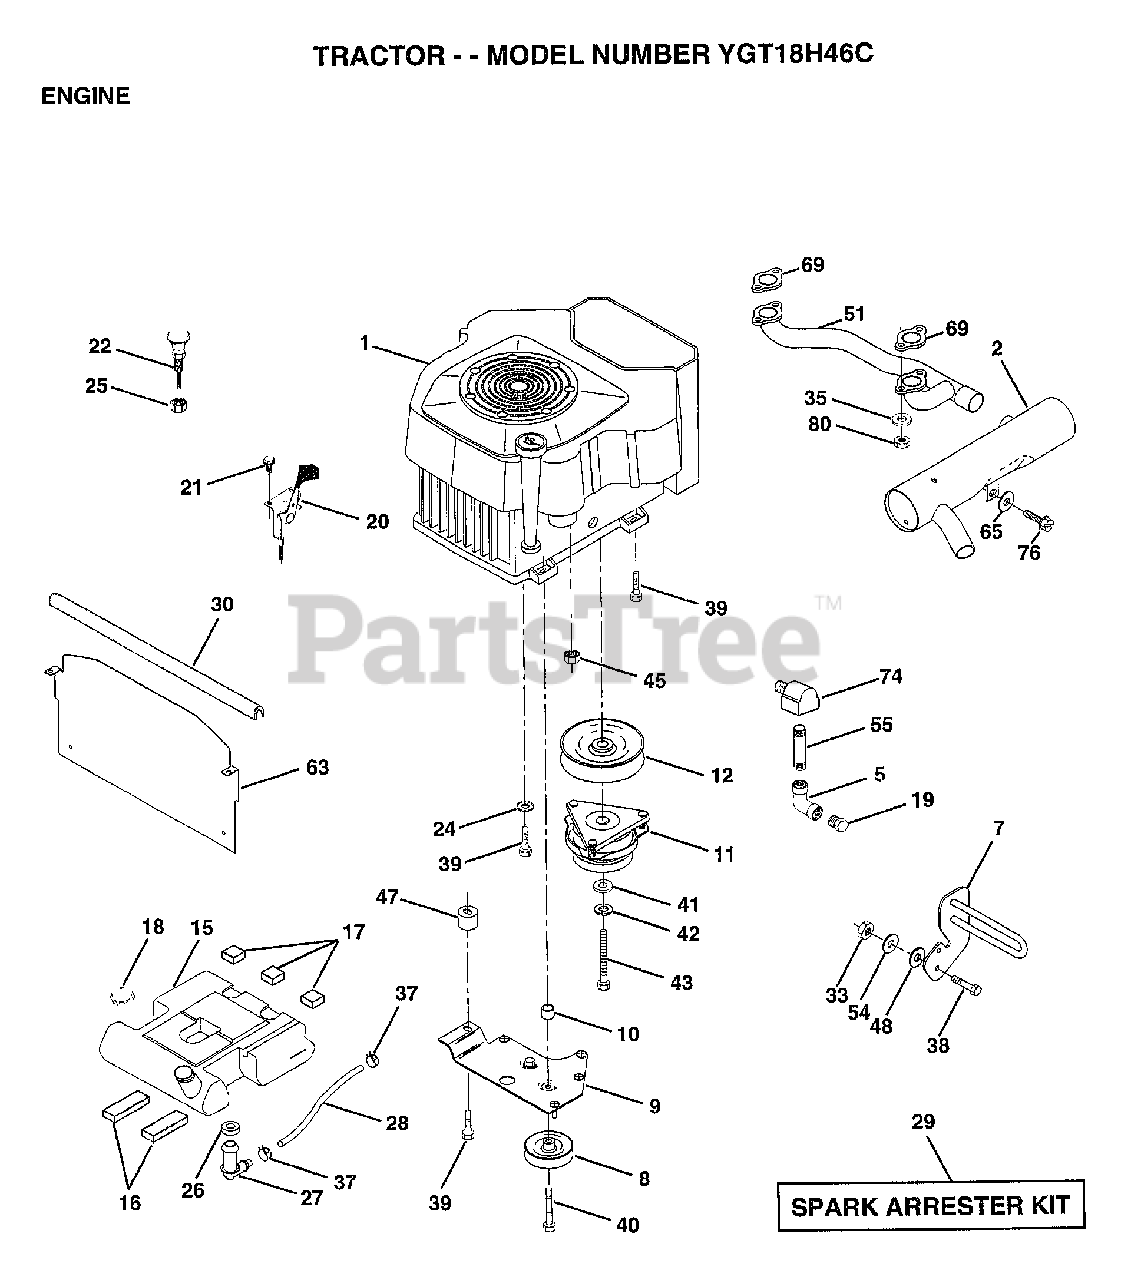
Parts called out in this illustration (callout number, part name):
2	MUFFLER.SIDE.VGT
5	ELBOW
7	GUARD.MUFFLER.ASM
9	KEEPER ASM BELT
10	BUSHING.
12	PULLEY.ENG.CLUTCH
15	TANK FUEL REAR
16	PAD IDLER TI
17	PAD-SPACER LT
18	CAP ASM FUEL
19	PLUG T
21	SCREW LT
22	CHOKE CONTROL
24	LOCKWASHER
25	"NUT,KEPS 3/8-24IM"
26	BUSHING OUTLET T
27	STEM.TANK.FUEL
29	SPARK ARREST KIT
30	EXTRUSION HOOD
33	NUT
35	WASHER.SPLIT
37	HOSE CLAMP
38	"BOLT,HEX"
39	SCREW.3/8-16X2.25
40	SCREW.TT.3/8-16X4
41	WASHER
42	LOCKWASHER
43	BOLT.7/16-20X4.25
45	NUT
47	SPACER.ENGINE
48	WASHER T
51	MANIFOLD.PIPE.VGT
54	WASHER
55	PIPE NIPPLE LT
63	HEAT.SHIELD.VGT.
65	WASHER
69	GASKET
74	ELBOW STREET BASS
76	SCREW
80	NUT FLANGE M8-125
